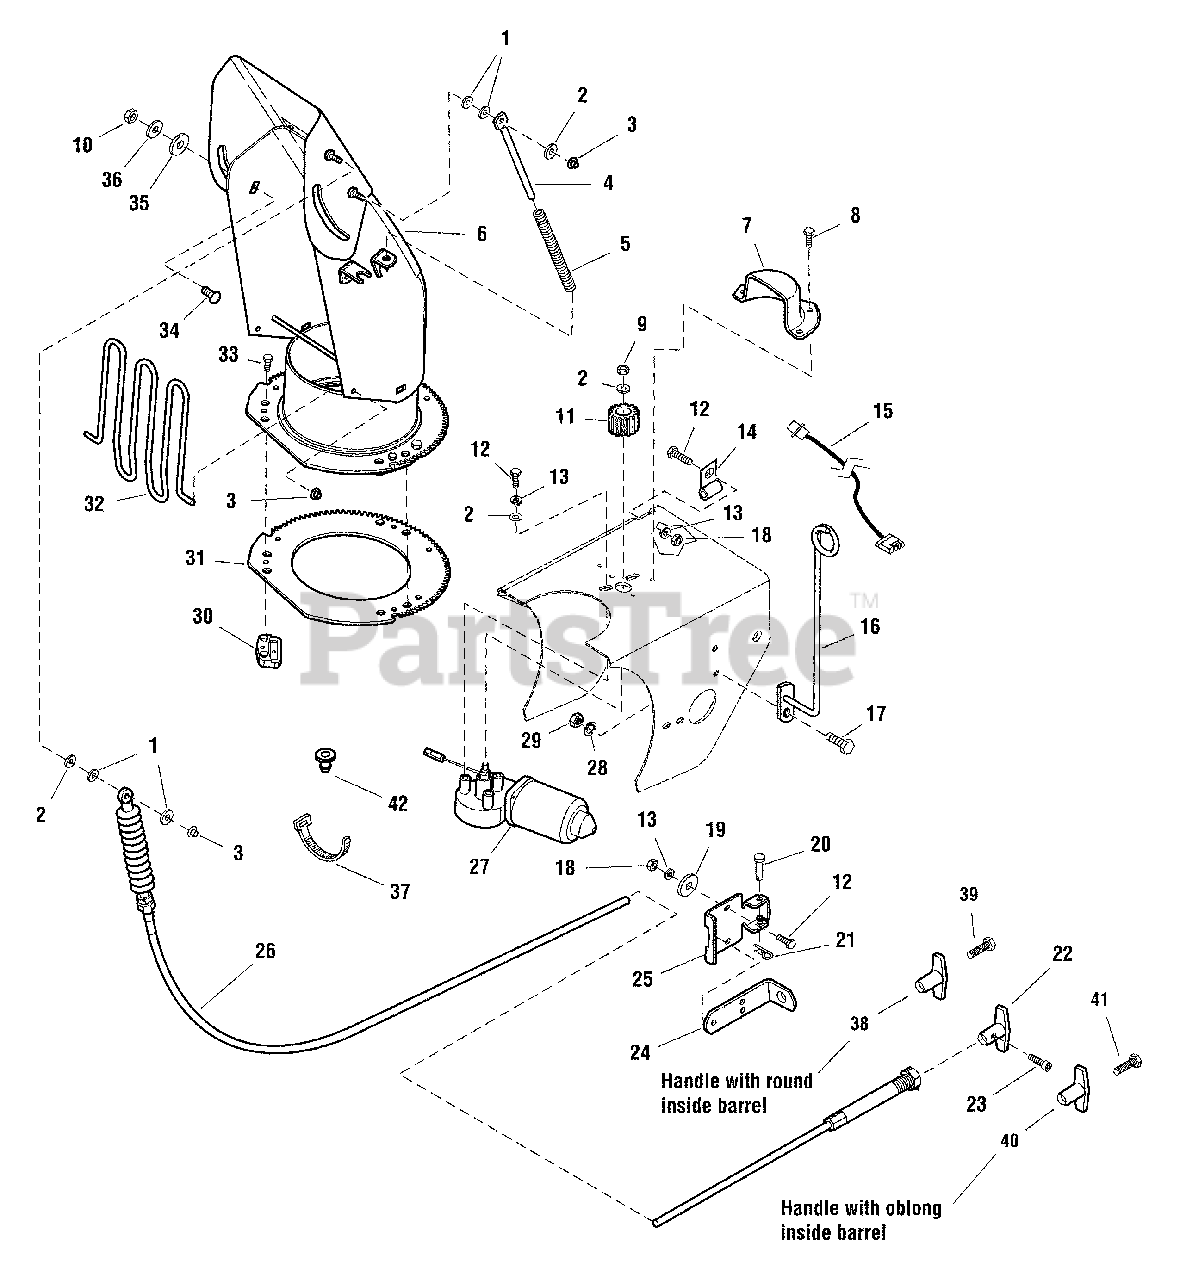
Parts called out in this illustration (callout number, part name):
2	WASHER,1/4
3	NUT, Push, 1/4
6	CHUTE & DEFLECTOR ASSEMBLY
7	COVER, Pinion
8	SCREW, Hex Head, Taptite, 1/4-20 x 1/2
9	NUT, Hex, Centerlock, 1/4-20
10	NUT, Hex Lock ESNA 5/16-18
11	PINION, 15 Teeth
12	CAPSCREW, Hex Head, 1/4-20 x 7/8
13	LOCKWASHER, 1/4
14	CLAMP, Wire
15	HARNESS ASSEMBLY
16	ROD & BAR ASSEMBLY
17	CAPSCREW, Hex Head, 5/16-18 x 1
18	NUT, Hex, 1/4-20
19	WASHER, 1/4
20	PIN, Flat Head Drilled
21	CLIP, Hair Pin
23	SCREW, Set Hex #10-24 x 3/8
26	CABLE & KNOB ASSEMBLY
27	MOTOR, Electric
28	LOCKWASHER, 5/16
29	NUT, Hex, 5/16-18
30	PLATE, Hold Down
32	GUARD & SUPPORT ASSEMBLY
33	CAPSCREW, Hex Head, Taptite, #10-24 x 7/8
34	CARRIAGE BOLT, 5/16-18 x 3/4
36	WASHER, 5/16
38	HANDLE "T"
39	SCREW, Round Head
40	HANDLE "T"
41	SCREW, #8c x 3/4
42	CAP, Plug Black Poly
